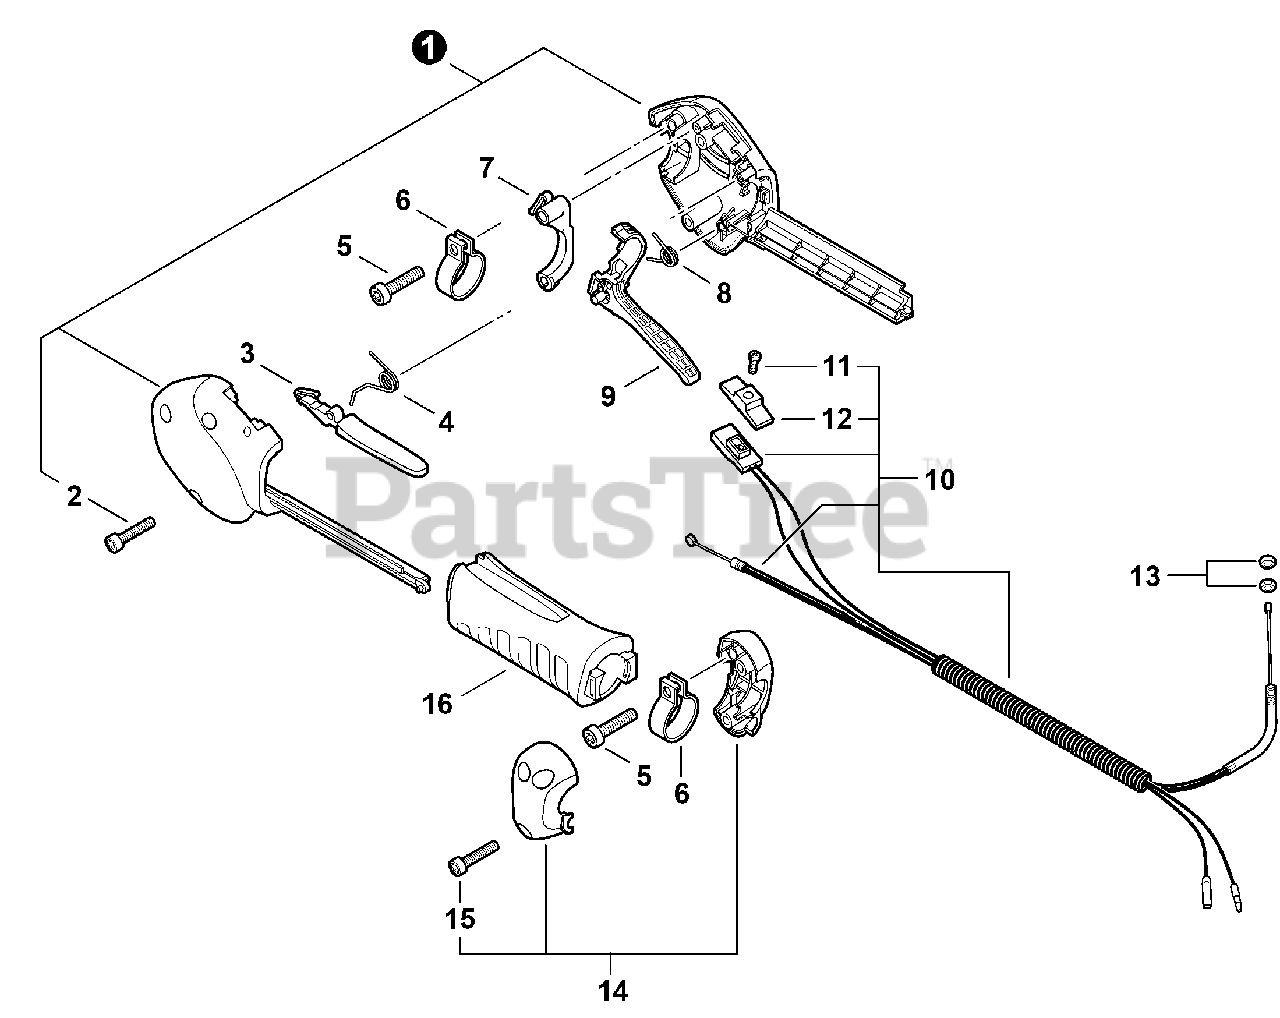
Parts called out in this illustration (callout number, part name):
1	CONTROL HANDLE KIT
2	SCREW - 4×22 -- TAPPING
3	LEVER, THROTTLE LOCKOUT
4	SPRING, LEVER RETURN
5	SCREW - 5×20
7	LOCKOUT, TRIGGER
8	SPRING, TRIGGER
9	TRIGGER, THROTTLE
10	CONTROL CABLE ASY
11	SCREW - 3×10
12	KNOB, SWITCH - ORANGE
14	HANDLE FIXTURE KIT
15	SCREW - 4×22 -- TAPPING
16	GRIP, HANDLE
